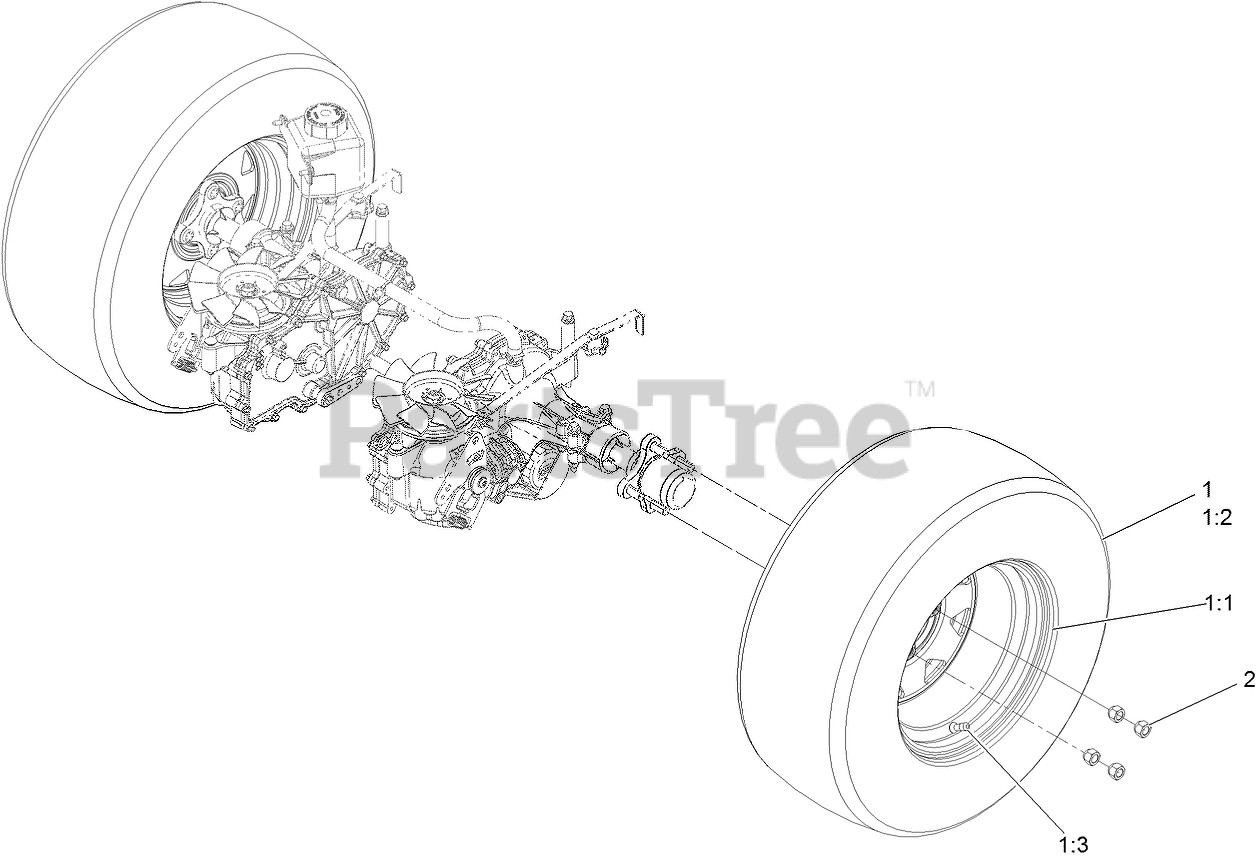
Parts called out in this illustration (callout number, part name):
1	WHEEL AND TIRE ASM
1:1	WHEEL-12X7, 8 SPOKE 4 ON
1:3	Stem-Valve
2	NUT-LUG
